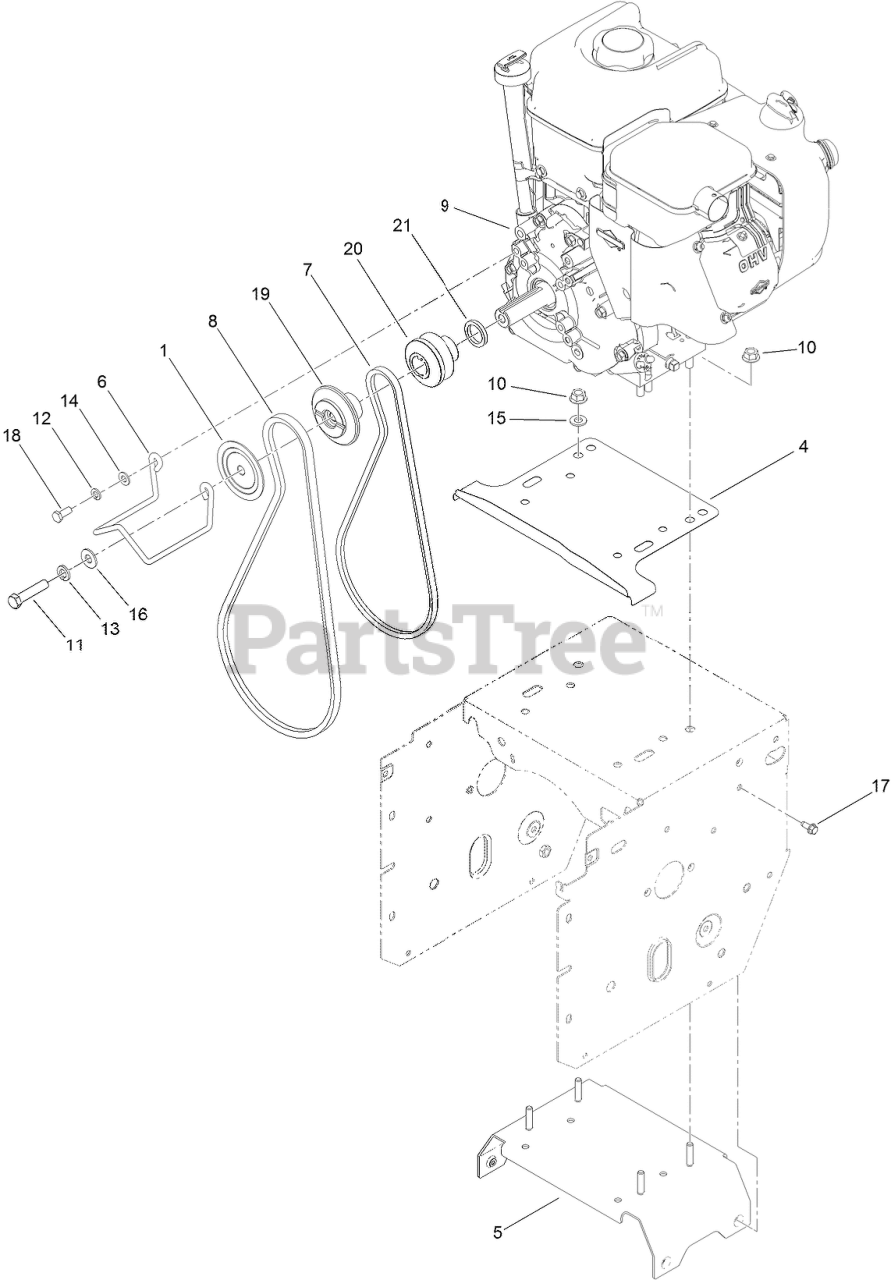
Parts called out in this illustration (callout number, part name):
1	SHEAVE-HALF, IMPELLER
4	SHIELD-DRIVE
5	FRAME BRACE ASM
6	GUIDE-BELT
7	V BELT-TRACTION
8	BELT-V
10	NUT-HF
11	SCREW-HH
12	WASHER-LOCK
13	WASHER-LOCK
14	WASHER-PLAIN
15	WASHER-FLAT
16	WASHER-FLAT
17	SCREW-HWH
18	SCREW-HH
19	PULLEY-ENGINE, IMPELLER
20	PULLEY-TRACTION
21	SPACER-HARDENED
